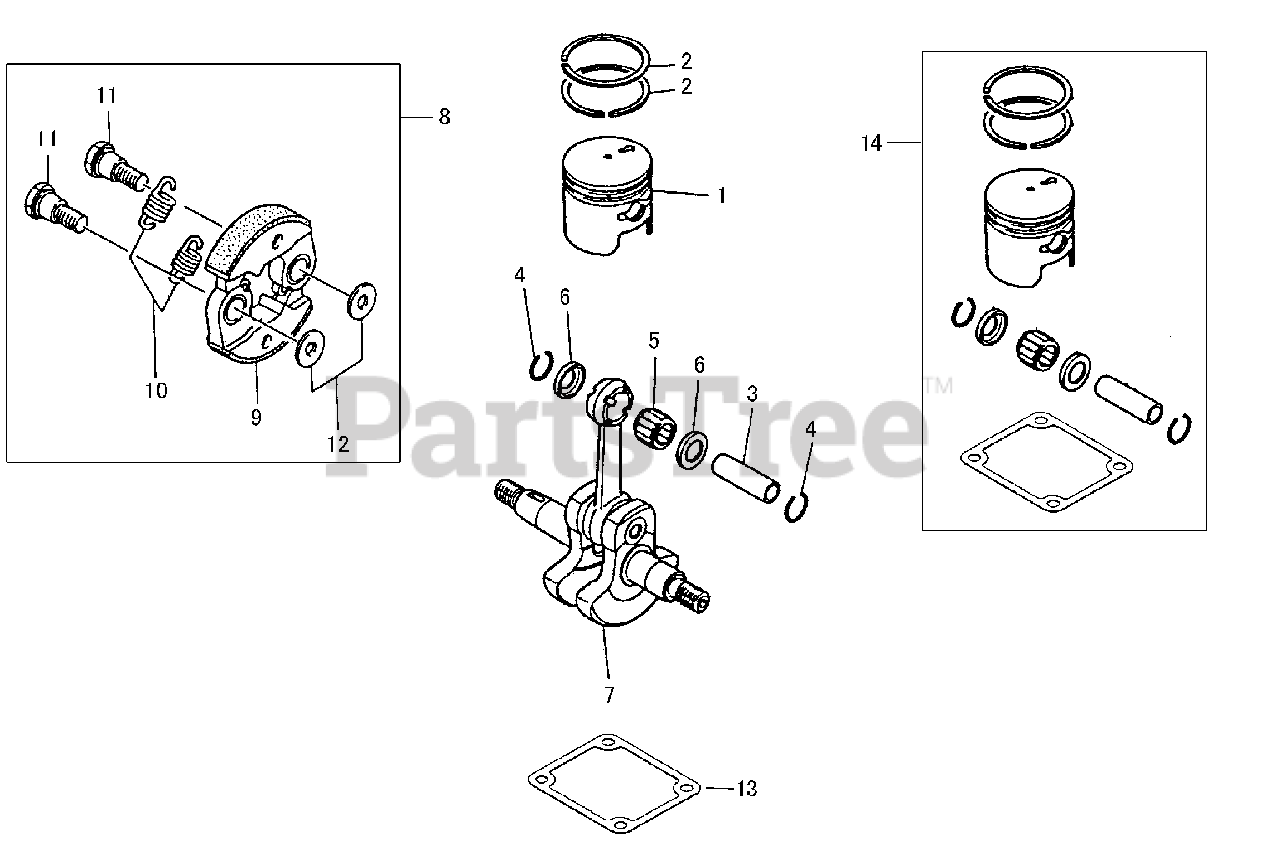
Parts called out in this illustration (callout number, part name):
1	PISTON
2	RING, PISTON
3	PIN, PISTON 10
4	RING, SNAP
5	BEARING, NEEDLE 10
6	WASHER, THRUST
7	CRANKSHAFT ASSY
8	SHOE ASSY, CLUTCH
9	SHOE, CLUTCH
10	SPRING, CLUTCH
11	BOLT, CLUTCH
12	WASHER
13	GASKET, CYLINDER
14	PISTON KIT
